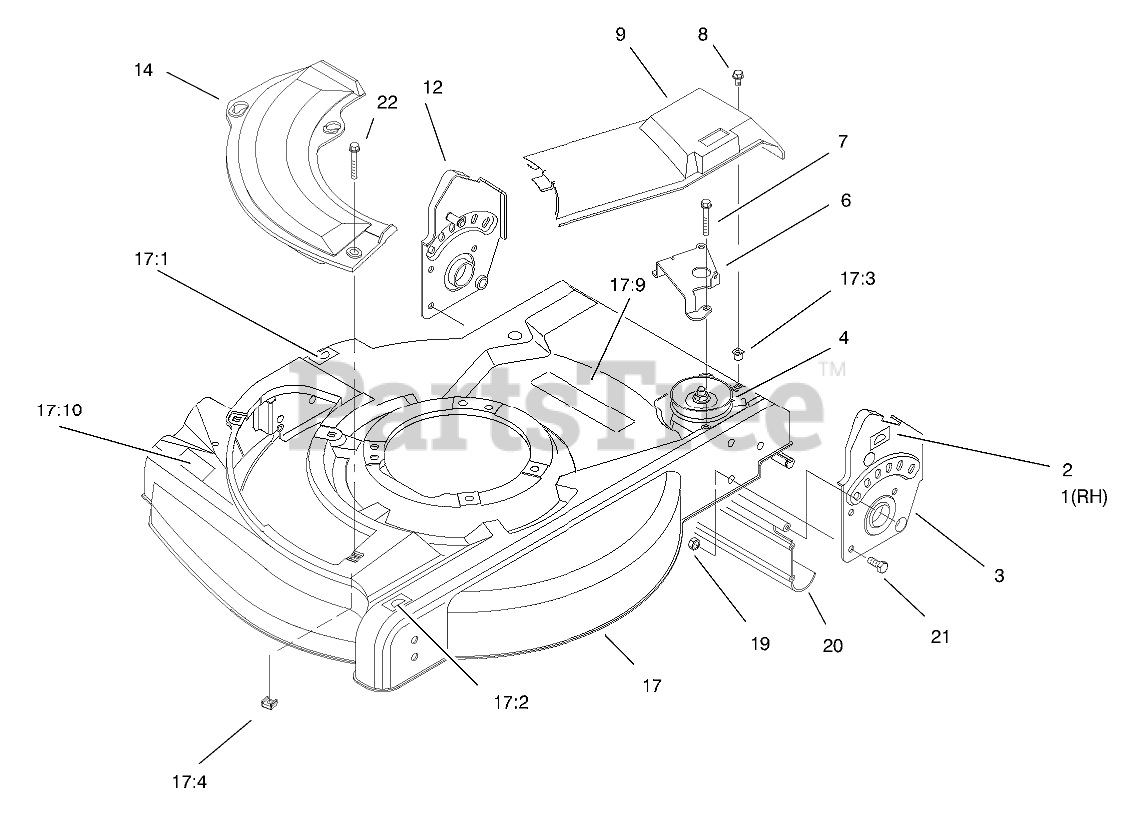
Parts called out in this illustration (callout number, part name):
7	SCREW-HWHTF
8	SCREW-TAP
9	COVER-DRIVE
14	PLATE-OPENING, CHUTE
17	HOUSING
17:1	DECAL-HOC, RH
17:2	DECAL-HOC, LH
17:3	NUT-CLIP
17:4	NUT-CAGE
17:9	DECAL-DANGER
17:10	DECAL-WARNING
19	NUT-LOCK, NI
20	SHIELD-TRAILING
21	SCREW-HH
22	SCREW-HWH
